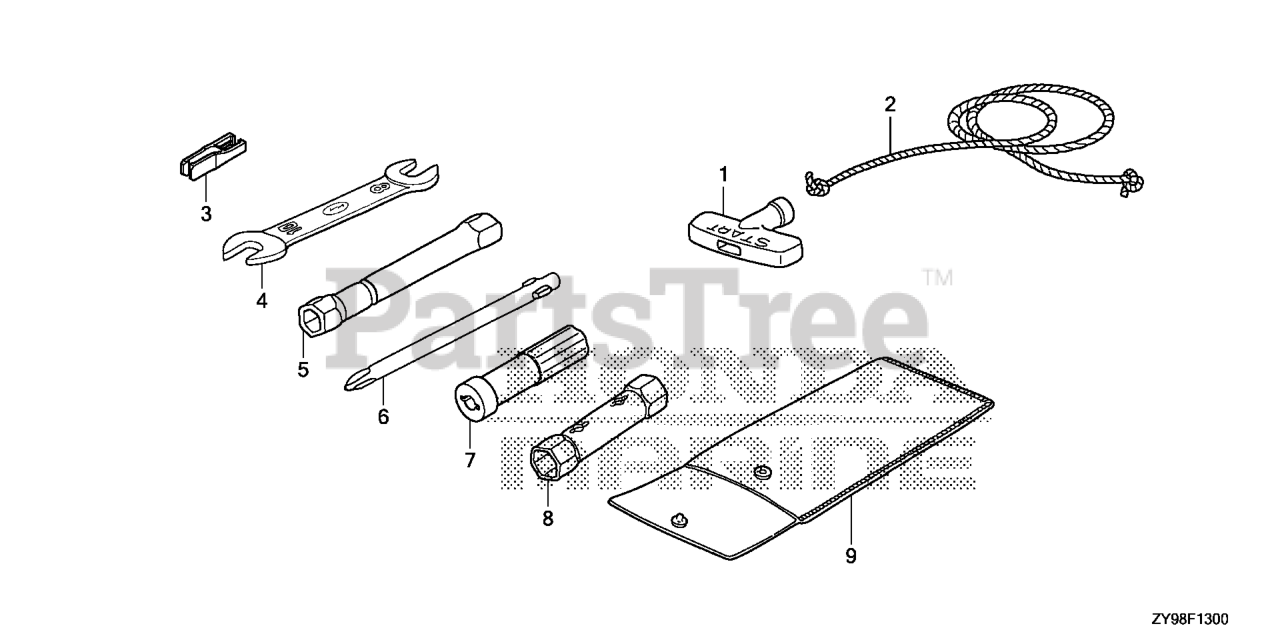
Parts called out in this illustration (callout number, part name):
1	GRIP, STARTER
2	ROPE, RECOIL STARTER (1300MM)
3	PULLER, MINI FUSE (SUMITOMO)
4	SPANNER (8X10)
5	WRENCH, PLUG
6	SCREWDRIVER 1, PHILLIPS (NO.2)
7	GRIP, SCREW DRIVER
8	WRENCH, BOX (P18X19)
9	BAG, TOOL (200MM)
